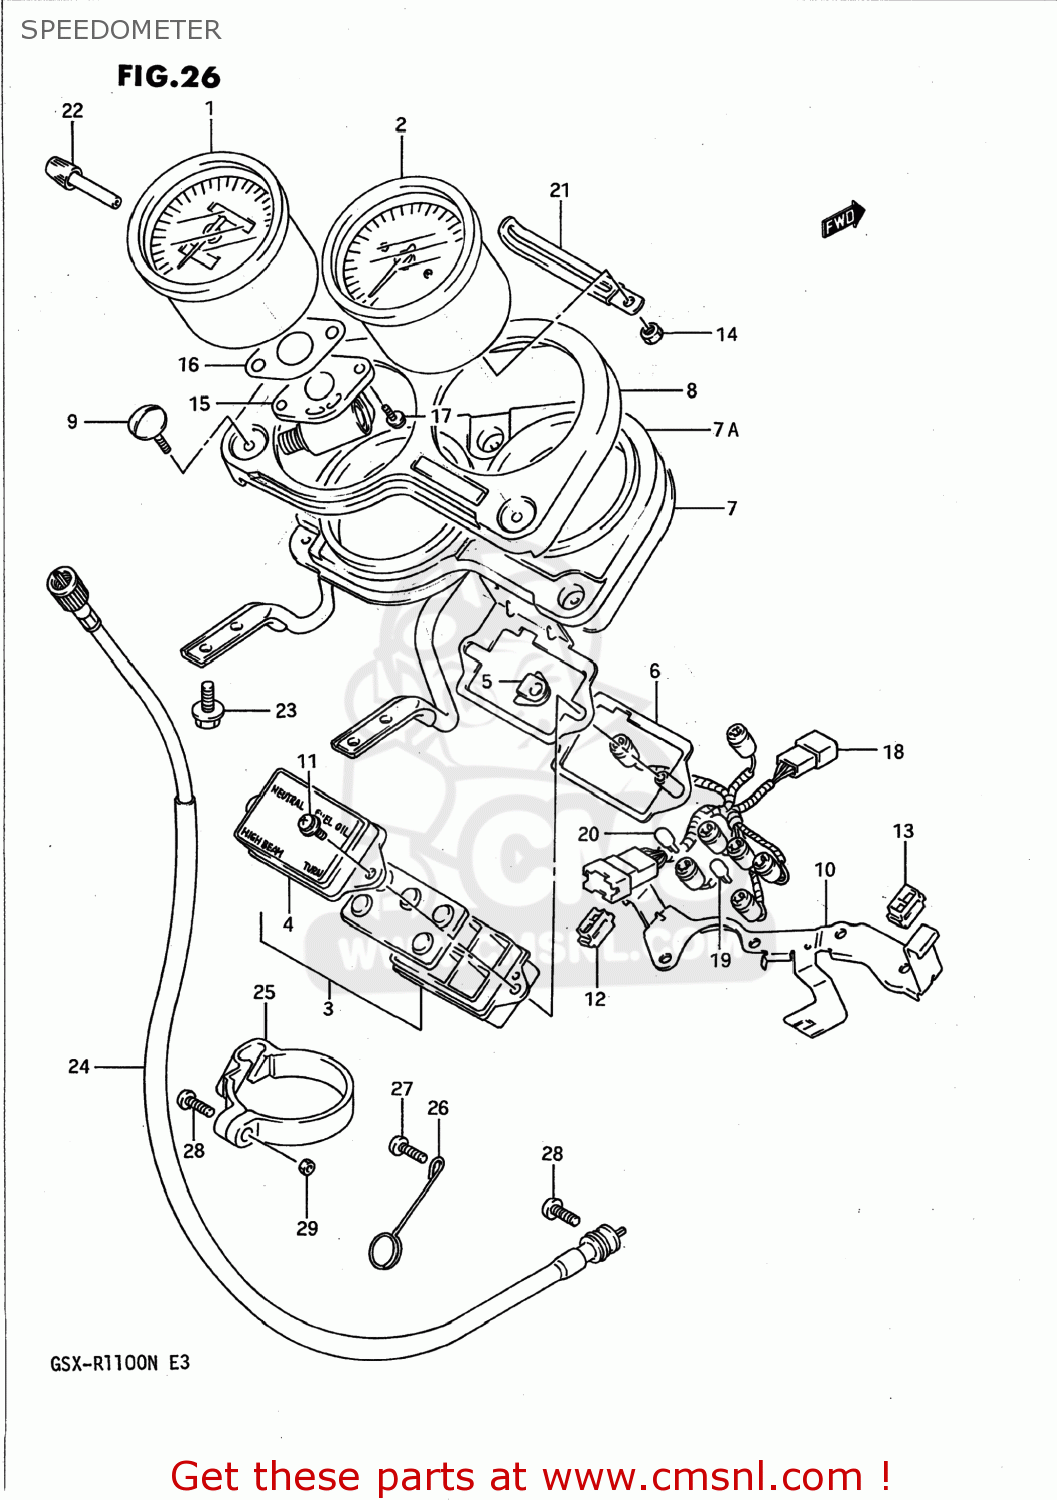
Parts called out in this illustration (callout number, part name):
1	SPEEDOMETER ASSEMBLY
2	TACHOMETER
3	BOX ASSEMBLY,PILOT LAMP
4	LENS,BOX
5	DAMPER
6	PLATE,SETTING
7	PLATE
7A	CUSHION
8	PANEL,METER
9	BOLT,SETTING
10	BRACKET
11	SCREW
12	DAMPER,LEFT
13	CUSHION
14	NUT
15	GEAR BOX
16	GASKET,METER GEAR BOX (NAS)
17	SCREW
18	SOCKET
19	BULB(12V3W,T6.5)
20	BULB(12V1.7W,T6.5)
21	CLAMP
22	KNOB,TRIP
23	BOLT 6X12
24	CABLE ASSEMBLY,SPEEDOMETER
25	GUIDE,METER CABLE NO.2
26	GUIDE,SPEEDOMETER CABLE NO.3
27	SCREW
28	SCREW
29	NUT 5MM
